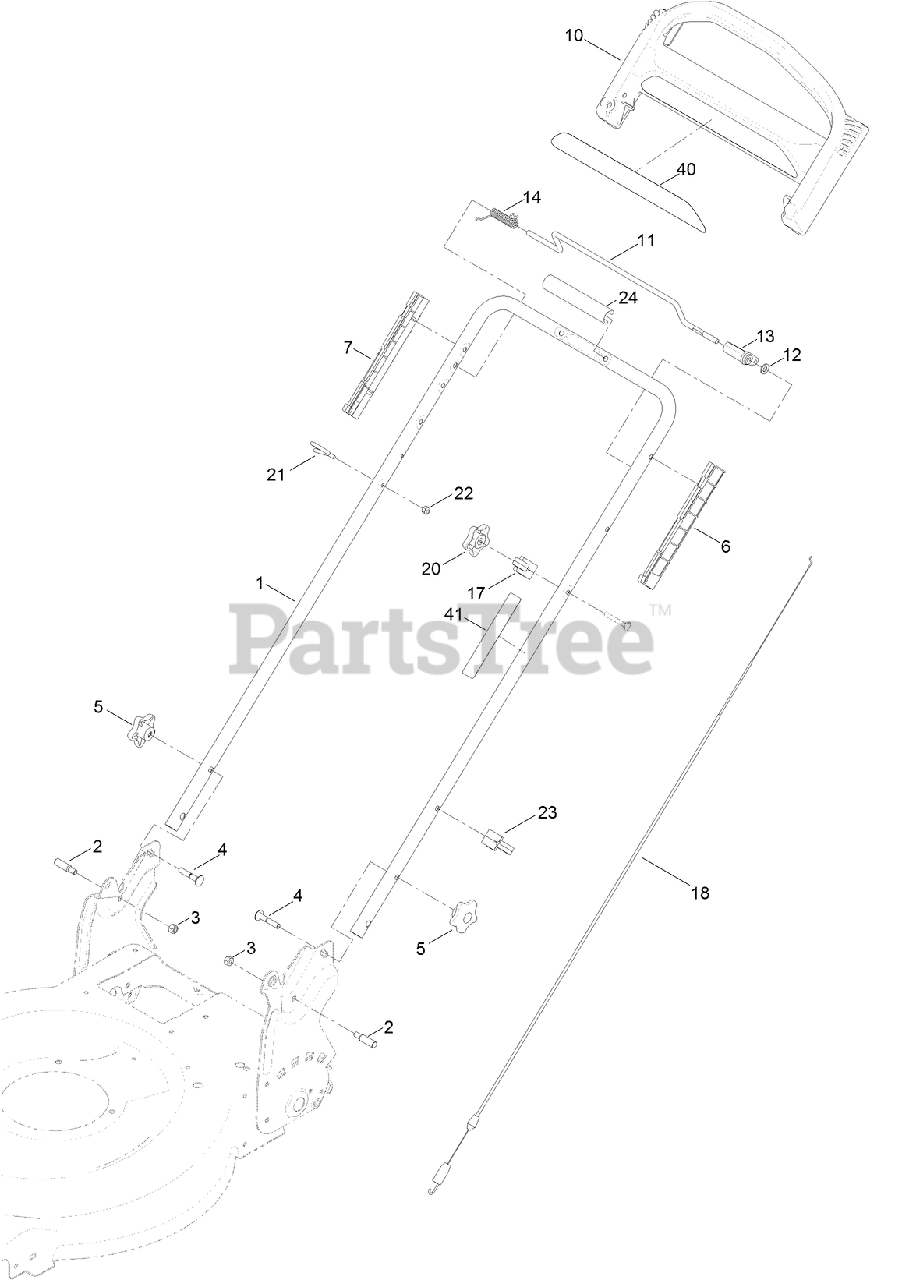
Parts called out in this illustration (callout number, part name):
2	BOLT-SHOULDER
3	NUT-LOCK, NI
4	SCREW-CARR
5	KNOB-HANDLE
6	GUIDE-LH
7	GUIDE-RH
10	HANDLE-CONTROL
12	WASHER-PLAIN
13	LEVER-TRACTION
18	CABLE-TRACTION
20	KNOB-HANDLE, LOCKING
21	GUIDE-ROPE
22	NUT-LOCK, NI
23	GUIDE-CABLE
24	HANDLE-COVER
41	DECAL-TRACTION, ADJUST
